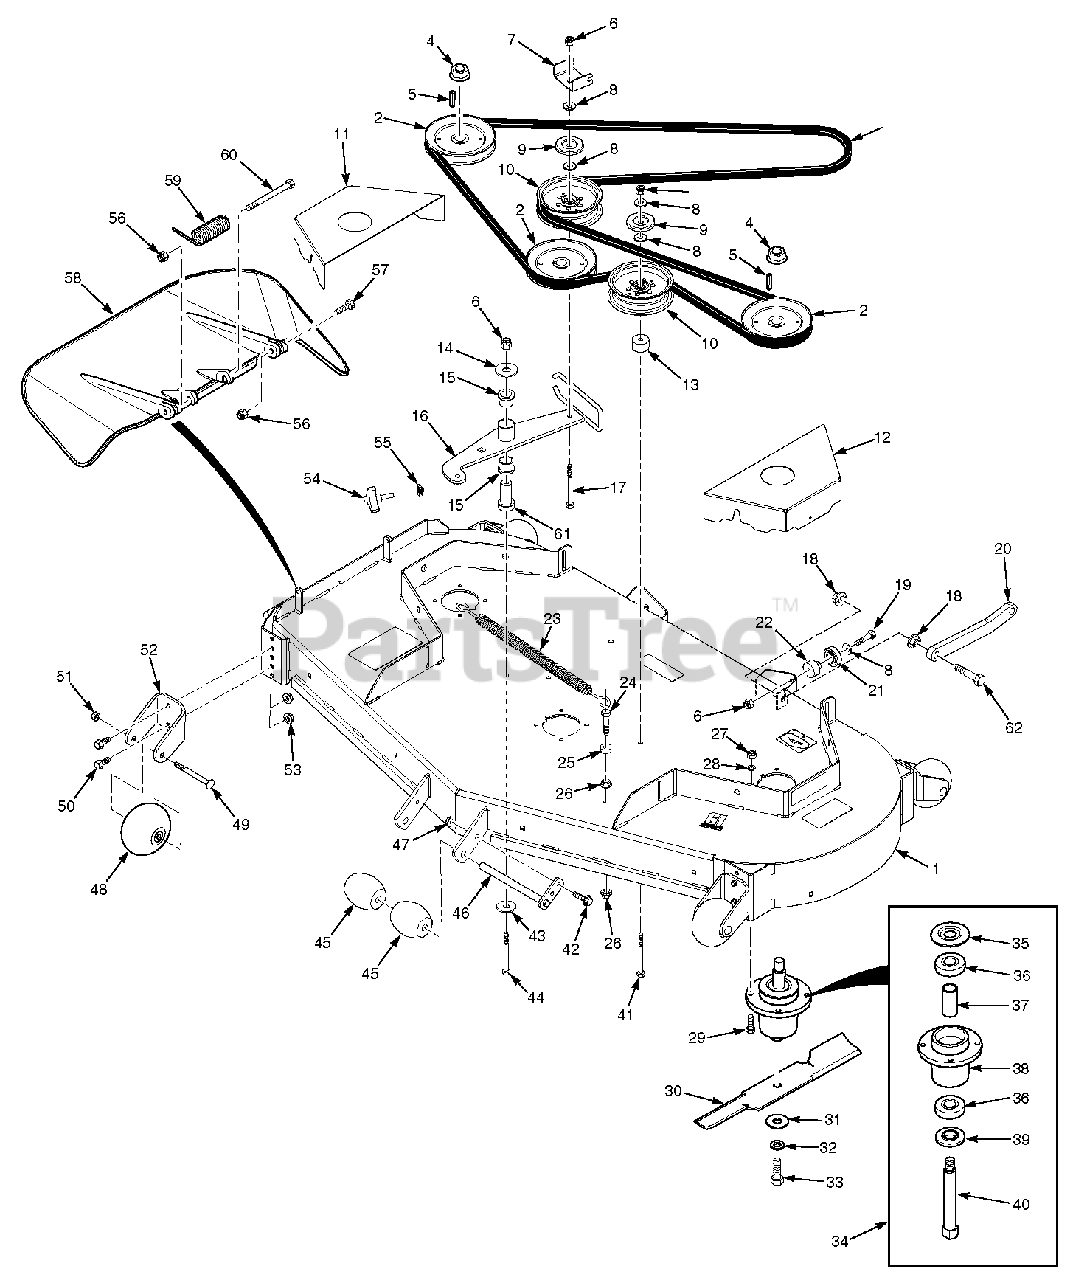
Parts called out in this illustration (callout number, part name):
1	Cutter Deck w/Decals, SWZT61
2	Pulley, 6.32" Dia.
3	Belt, Cutter Deck - SWZT61
4	Nut, Spiral Lock 3/4-16
5	Key, 1/4 x 1/4 x 1-1/4"
6	Nut, Elastic Stop 3/8-16
7	Bracket, Belt Guide
8	Flatwasher, 3/8-.391 x .938 x .105
9	Dust Shield
10	Pulley, Idler 5"
11	Belt Cover, RH - SWZT61
12	Belt Cover, LH - SWZT61
13	Spacer
14	Flatwasher, 3/8-.406 x 1-1/2"
15	Bearing
16	Idler Arm Weldment w/Bearings - SWZT61
17	Bolt, Hex Head 3/8-16 x 2-1/2"
18	Nut, Serrated Flange 1/2-13
19	Bolt, Hex Head 3/8-16 x 2-1/4"
20	Pusharm
21	Bearing
22	Spacer, Bearing
23	Spring, Deck Idler
24	Bolt, Hex Head 3/8-16 x 1-1/2" Gr. 8
25	Spacer
26	Nut, Serrated Flange 3/8-16
27	Nut, Elastic Stop 5/16-18 Gr. 8
28	Lockwasher, 5/16" Spring
29	Bolt, Hex Head 5/16-18 x 1-1/2" Gr. 8
30	Cutter Blade, 21"
31	Flatwasher, 5/8-.688 x 1.75 x .134 HD
32	Lockwasher, 5/8" Spring
33	Bolt, Hex Head 5/8-11 x 1-1/2"
34	Spindle Assembly
35	Debris Shield
36	Bearing
37	Spacer
38	Spindle Housing
39	Protector, Bearing
40	Shaft, Spindle
41	Bolt, Hex Head 3/8-16 x 3-1/2"
42	Bolt, Heax Head 5/16-18 x 1"
43	Flatwasher, 3/8-.406 x 2.25 x .1875
44	Bolt, Hex Head 3/8-16 x 3-3/4"
45	Wheel, Anti-Scalp
46	Shaft Weldment
47	Nut, Serrated Flange 5/16-18
48	Wheel, Anti-Scalp
49	Bolt, Carriage 3/8-16 x 4"
50	Bolt, Hex Head Serrated Flange 3/8-16 x 1"
51	Nut, Center Lock 3/8-16
52	Bracket, Anti-Scalp
53	Nut, Serrated Flange 3/8-16
54	Knob w/Stud
55	U-Nut, 3/8-16
56	Nut, Elastic Stop 5/16-18
57	Bolt, Hex Head 5/16-18 x 1-3/4"
58	Discharge Chute Assembly
59	Spring, Discharge Chute
60	Bolt, Hex Head 5/16-18 x 4-3/4"
61	Pivot, Idler
62	Bolt, Hex Head 1/2-13 x 2"
